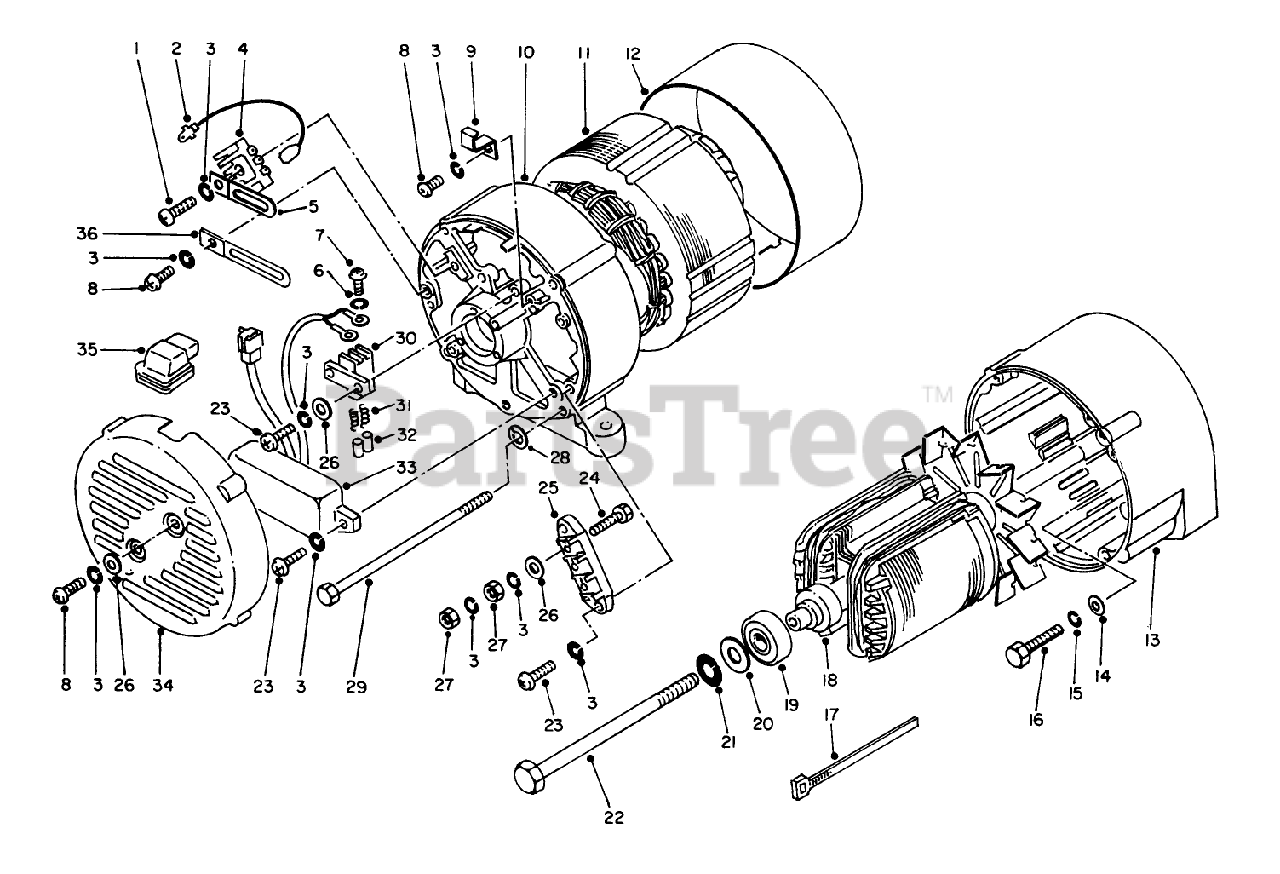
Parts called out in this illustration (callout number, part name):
15	WASHER-LOCK
28	LOCKWASHER
32	BRUSH
